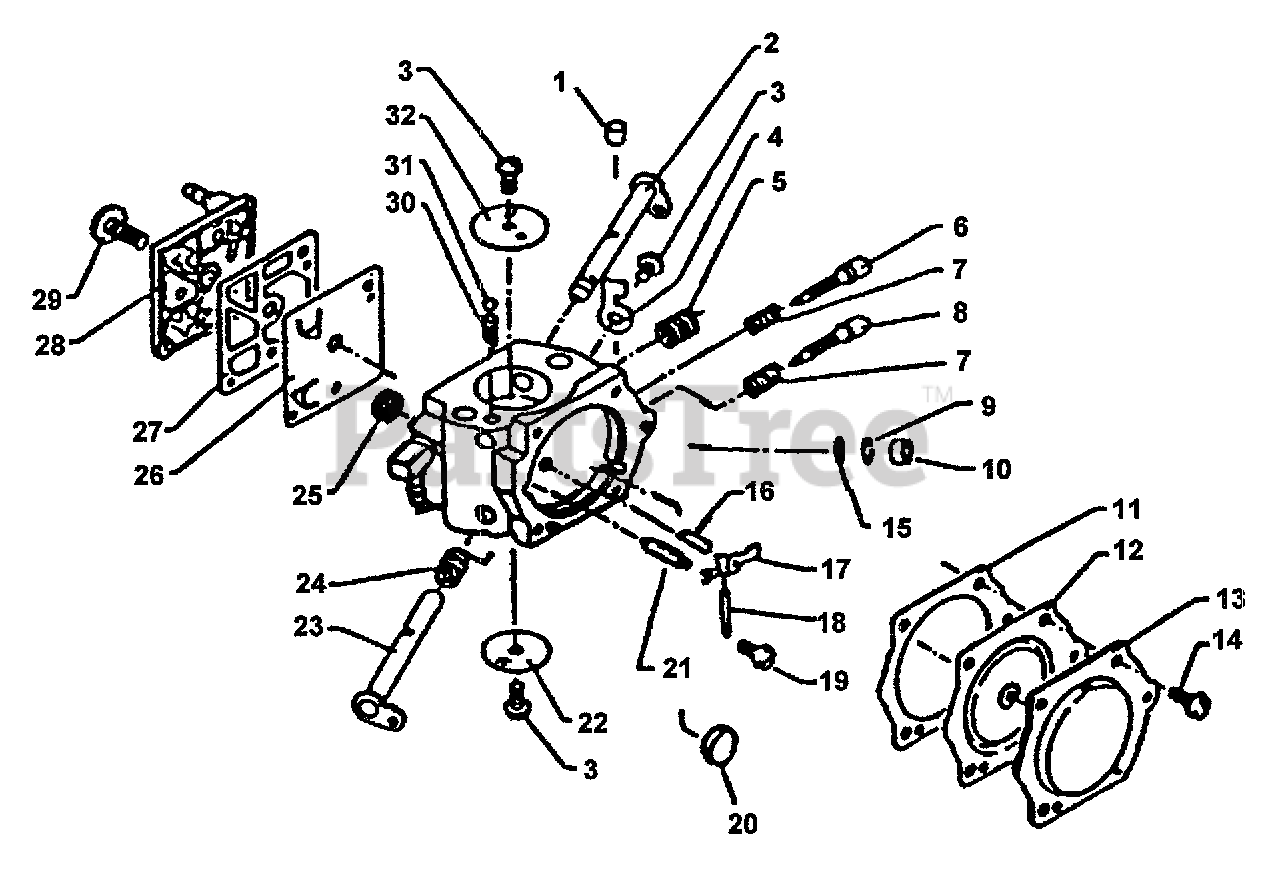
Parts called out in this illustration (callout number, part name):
1	PLUG, FRICTION
2	SHAFT, CHOKE
4	STOP, THROTTLE
5	SPRING, IDLE ADJUST
6	NEEDLE, IDLE
7	SPRING
8	NEEDLE, HIGH SPEED
9	RING, RETAINING
10	PLUG, WELCH
11	GASKET, METERING
12	DIAPHRAGM, METERING
13	COVER, METERING DIAPHRAGM
14	SCREW
15	STRAINER
16	SPRING, METERING LEVER
17	LEVER, METERING
18	PIN, METERING LEVER
19	SCREW, METERING LEVER PIN
20	PLUG, WELCH
21	VALVE, INLET NEEDLE
22	VALVE, THROTTLE
23	SHAFT, THROTTLE
24	SPRING, THROTTLE RETURN
25	STRAINER
28	COVER, FUEL PUMP
31	BALL, CHOKE FRICTION
32	VALVE, CHOKE
